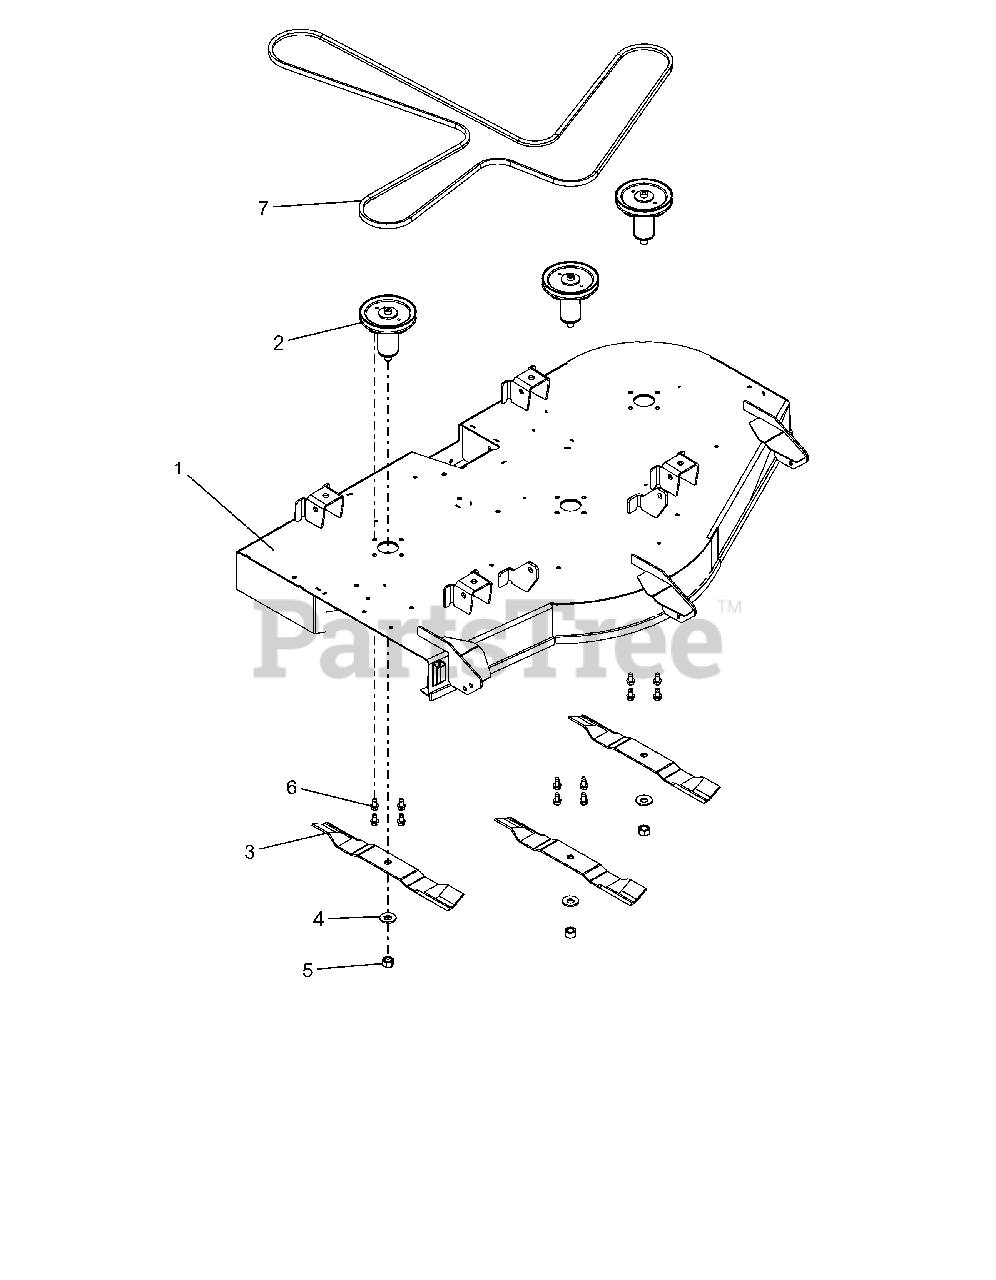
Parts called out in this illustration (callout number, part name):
1	KIT, 52" GRAVELY DECK W/DECALS
2	KIT, DECK SPINDLE ASM-52
3	BLADE, 18" - 30 DEG .5 OFFSET
4	WSHR-BLVL .669X1.535X.138
5	NUT-HEX .62-18 YWZC
6	@SCR-TAP .38-16X.75 HWH TR YWZ
7	V-BELT, HA-WRAPPED
